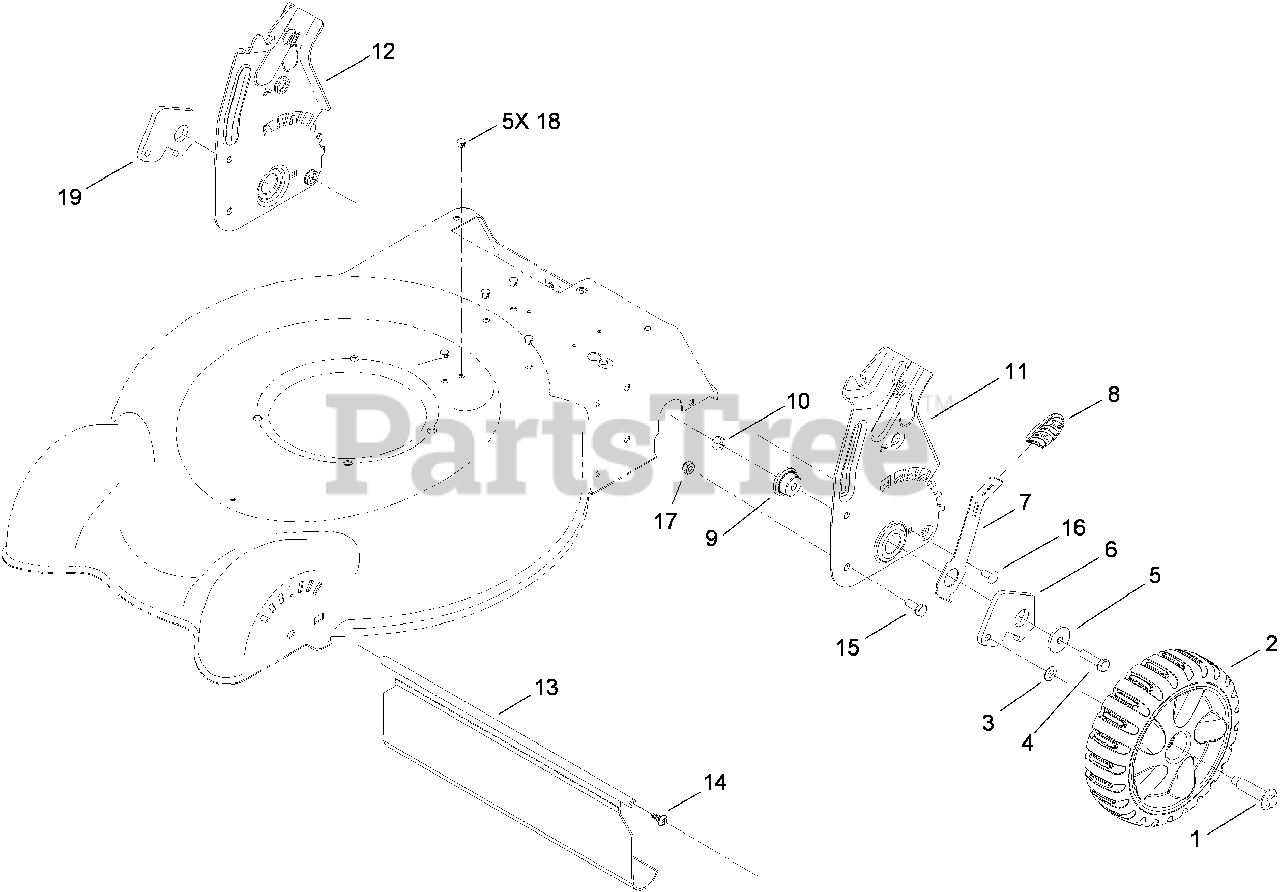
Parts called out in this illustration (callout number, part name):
1	BOLT-SHOULDER
2	8 INCH WHEEL ASM
4	SCREW-HH
5	Washer-Flat
6	Arm-Pivot, Rear (LH)
7	Arm-Spring
8	Knob-Lever, HOC
9	Bushing-Mount, HOC
10	NUT-LOCK, NI
11	PLATE-HOC, LH
12	PLATE-HOC, RH
13	SHIELD-TRAILING
14	SCREW-PTH
15	SCREW-HH
16	SCREW-CARR
17	NUT-LOCK, NI
18	Plug-Dome
19	ARM-PIVOT, REAR (RH)
